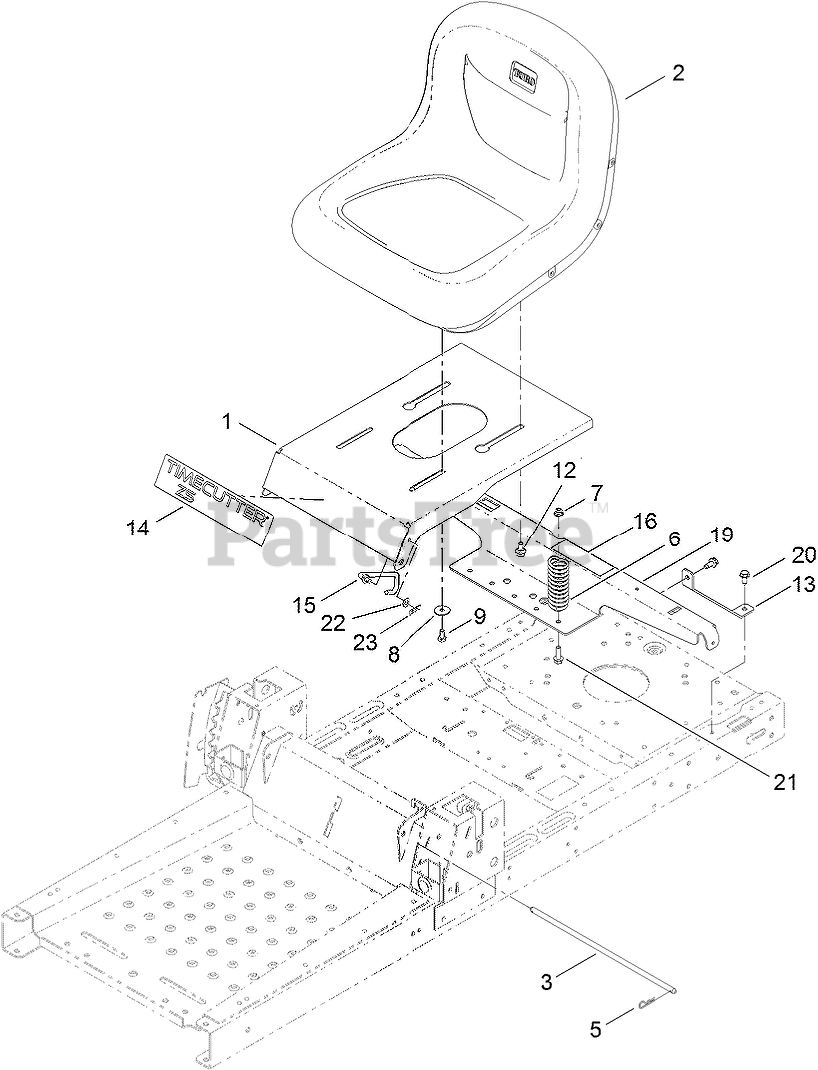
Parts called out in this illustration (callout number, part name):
1	PAN-SEAT
2	SEAT-15 INCH
3	ROD-PIVOT, NARROW
5	PIN-COTTER
6	SPRING-COMPRESSION
7	NUT-HF, NI
8	WASHER-PIVOT
9	SCREW-HH
12	BOLT-SHOULDER
13	SUPPORT-TANK, REAR
14	DECAL-TIMECUTTER
15	STOP-SEAT
16	DECAL-SERVICE, CE
19	SUPPORT-POD
20	SCREW-HWHTF
21	SCREW-HHF
22	WASHER-PLAIN
23	PIN-COTTER
